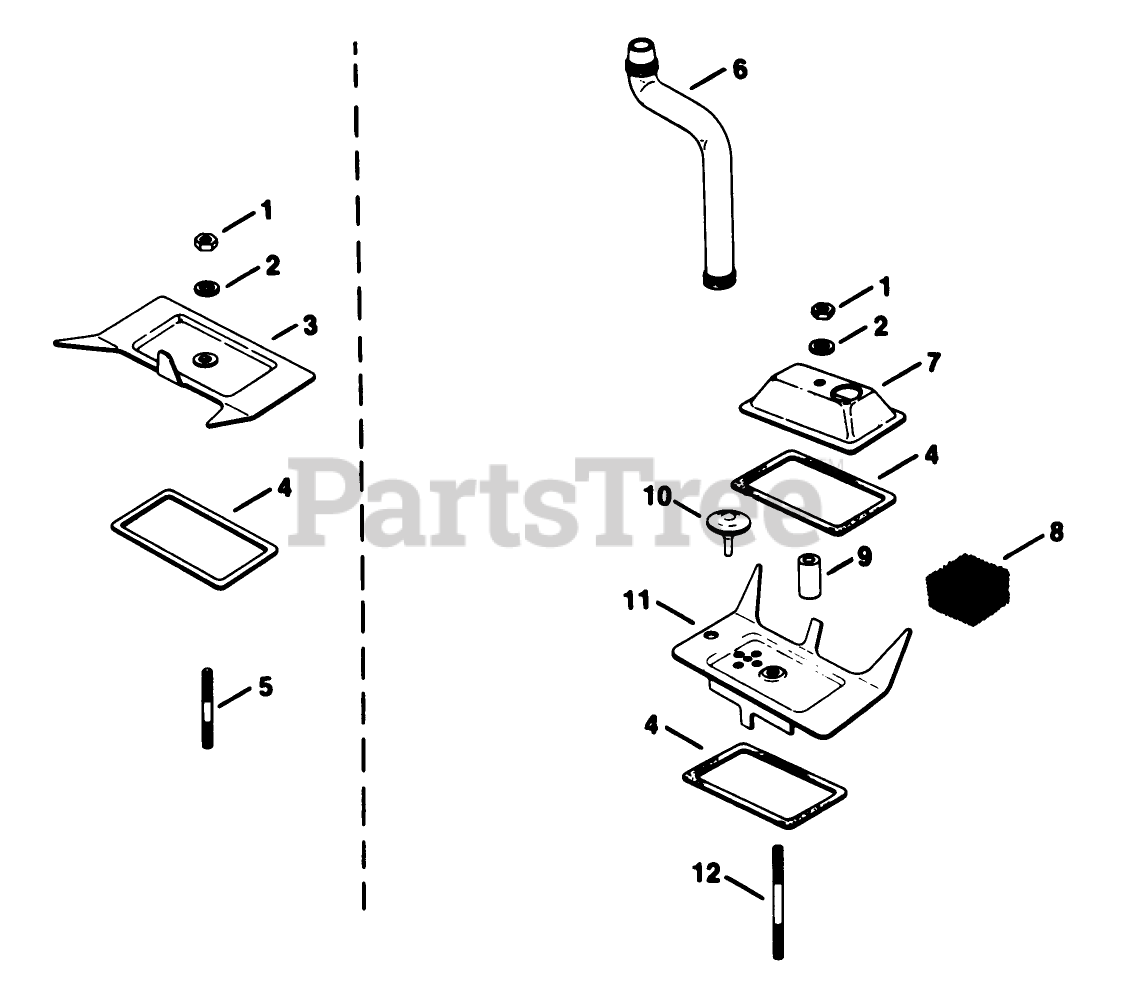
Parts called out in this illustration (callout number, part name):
2	Washer
3	Cover Cylinder Valve
4	Gasket-Cover
5	Stud-#2 Cyl Valve Cover
6	Hose-Breather
7	Cover-#1 Upper Cyl. Valve
8	Filter
9	Seal-Breather
10	Valve-Breather
11	Cover-#1 Lower Cyl. Valve
